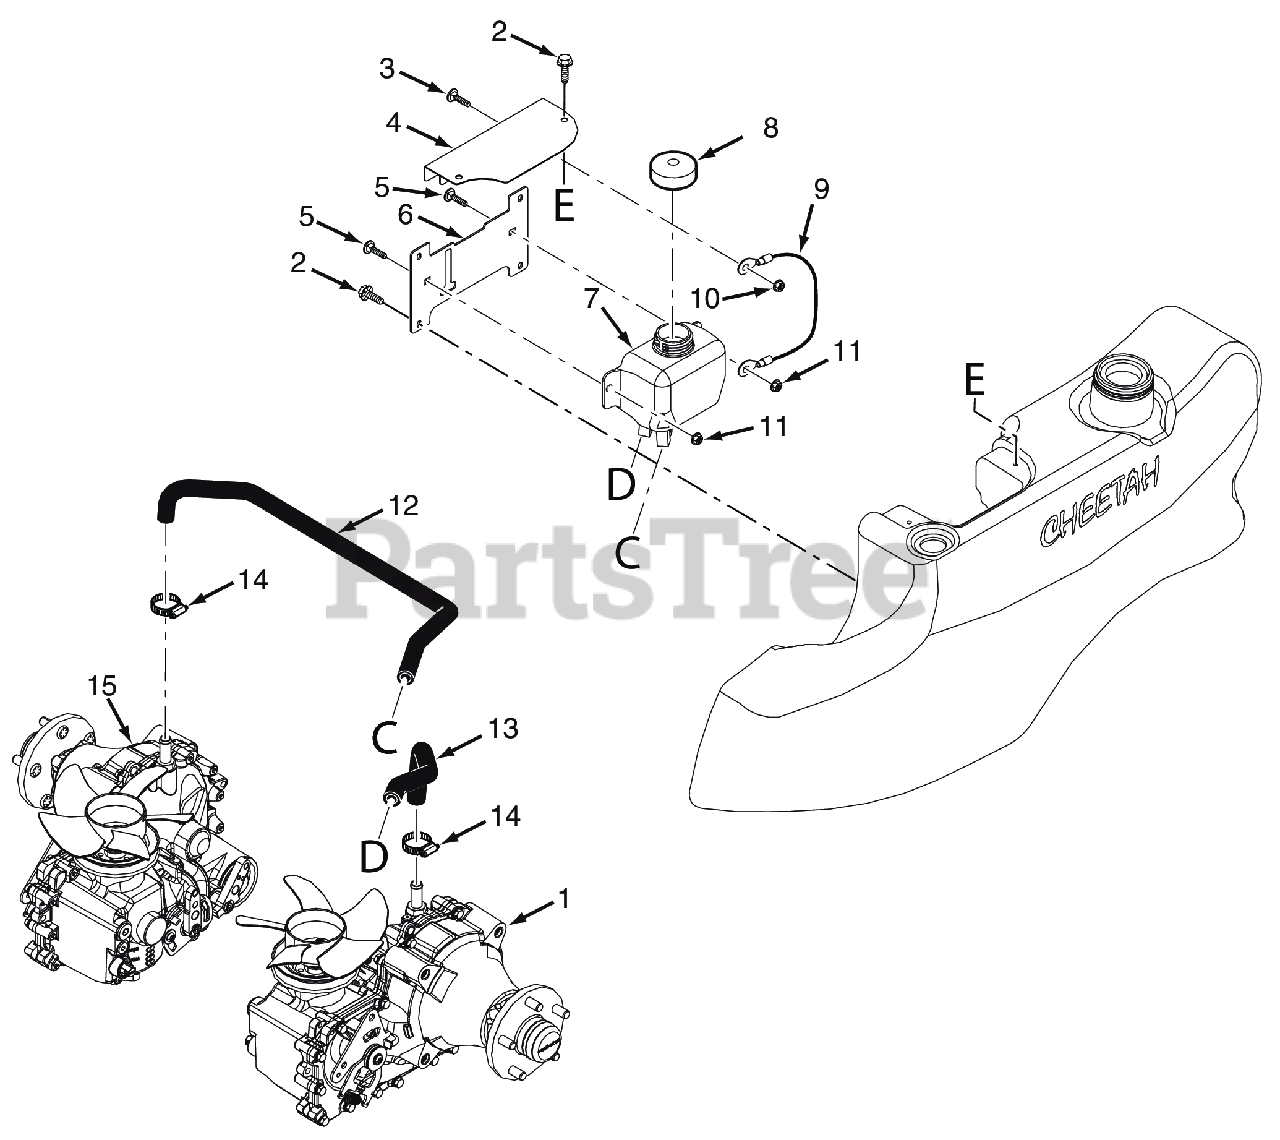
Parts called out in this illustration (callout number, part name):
1	Transaxle, LH
2	CAP SCREW, 1/4-20 X 1/2" SERRATED FLANGE HEX
3	Serr. Fl. Hex Head CPSCR, 1/4-20 x 3/4"
4	Cover, Oil Reservoir
5	Bolt, 5/16-18 x .75 RHSN Carriage
6	Plate, Hydro Tank Mount
7	Hydraulic Tank Assembly
8	Cap, Hydraulic Tank
9	Lanyard, Oil Reservoir Cover
10	HEX, NUT, ELASTIC STOP LOCK, 1/4-20
11	Nut, Flange Head Elastic Stop 5/16-18
12	Hose, RH Transaxle
13	Hose, LH Transaxle
14	Clamp, 1" Max Dia.
15	Transaxle, RH
